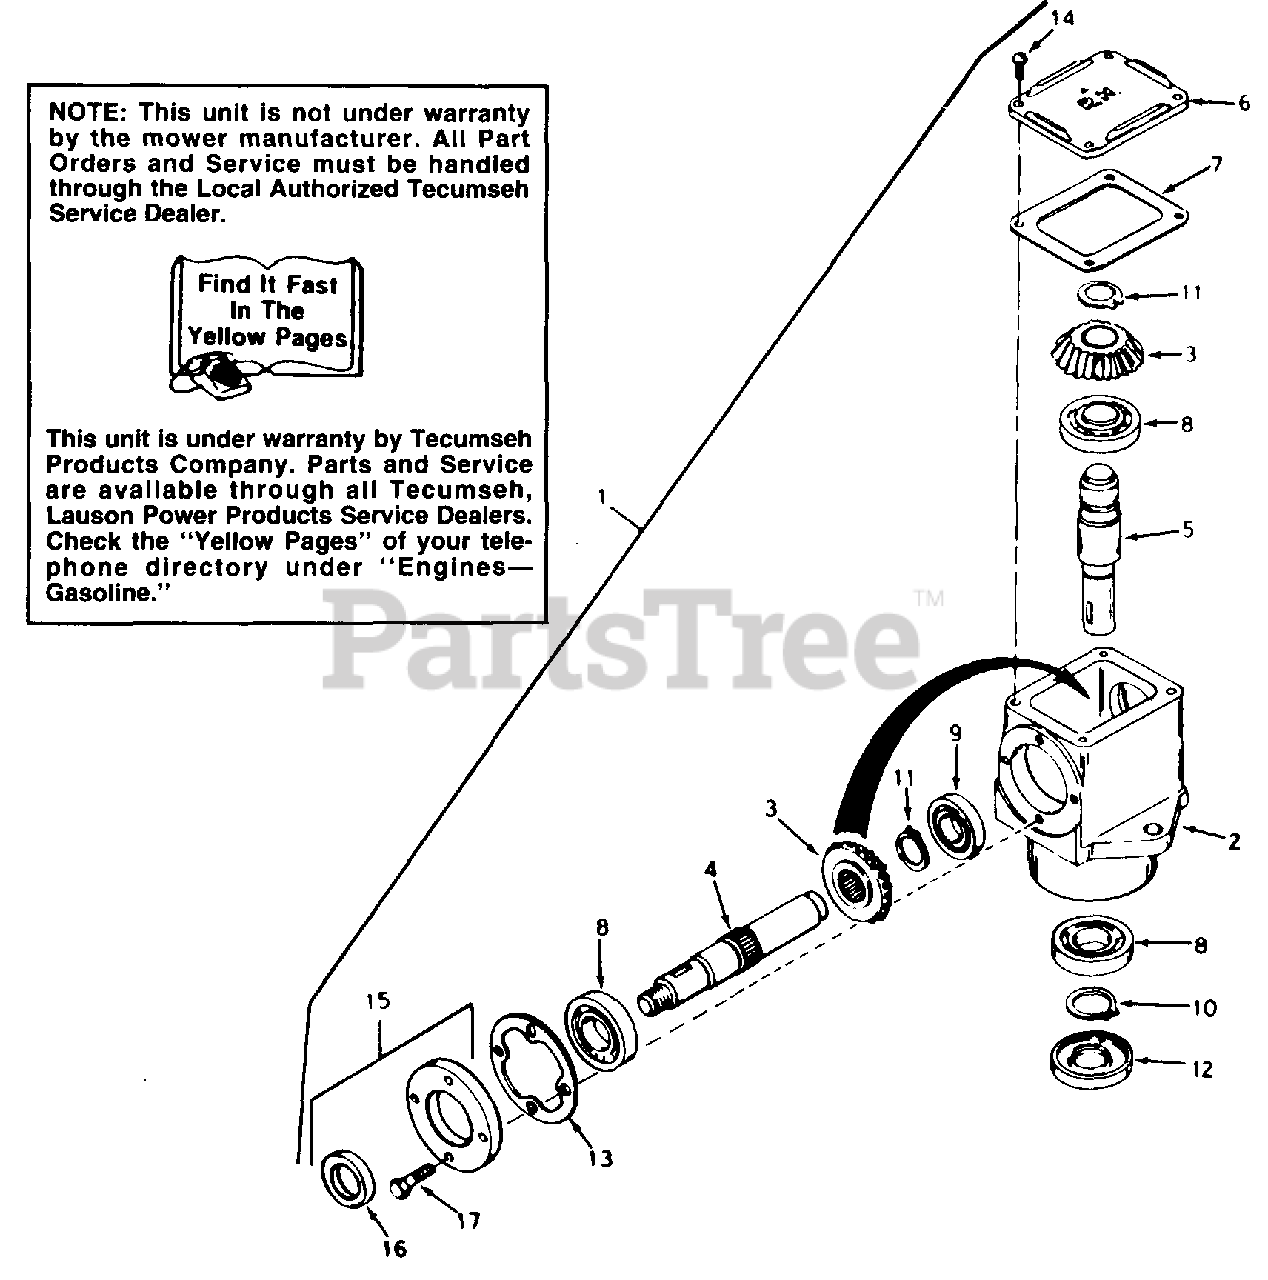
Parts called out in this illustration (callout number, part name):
1	Head Ass'y. R.H.
2	Housing, Right Angle Drive
3	Gear, Miter
4	Shaft, Input
5	Shaft, Output
6	Cover, Right Hand
7	Gasket, Cover
8	Bearing, Ball
9	Bearing, Ball
10	Ring, Snap
11	Ring, Snap
12	Seal, Oil
13	Gasket, Cap
14	Screw, Rd. Hd. Self-Tap. 10-24 x 1/2
15	Cap & Seal Ass'y., Retainer
16	Seal, Oil
17	Screw, Hex Hd. 1/4-20 x 7/8
